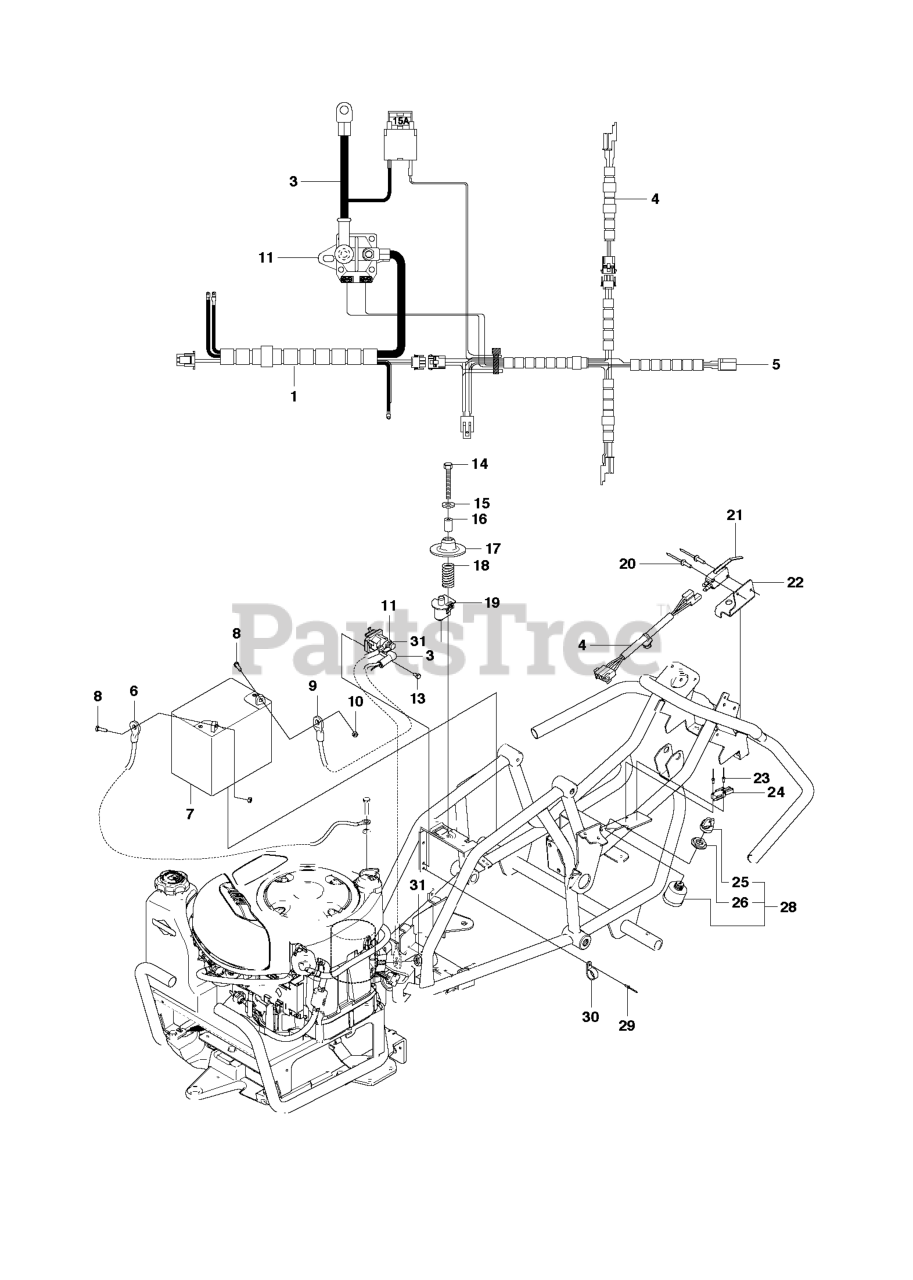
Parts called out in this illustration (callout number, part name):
8	SCREW EHHM
14	SCREW
16	SPACER TUBE
21	MICRO SWITCH
24	MICRO SWITCH
25	IGNITION KEY
28	IGNITION SWITCH
30	CABLE CLAMP
